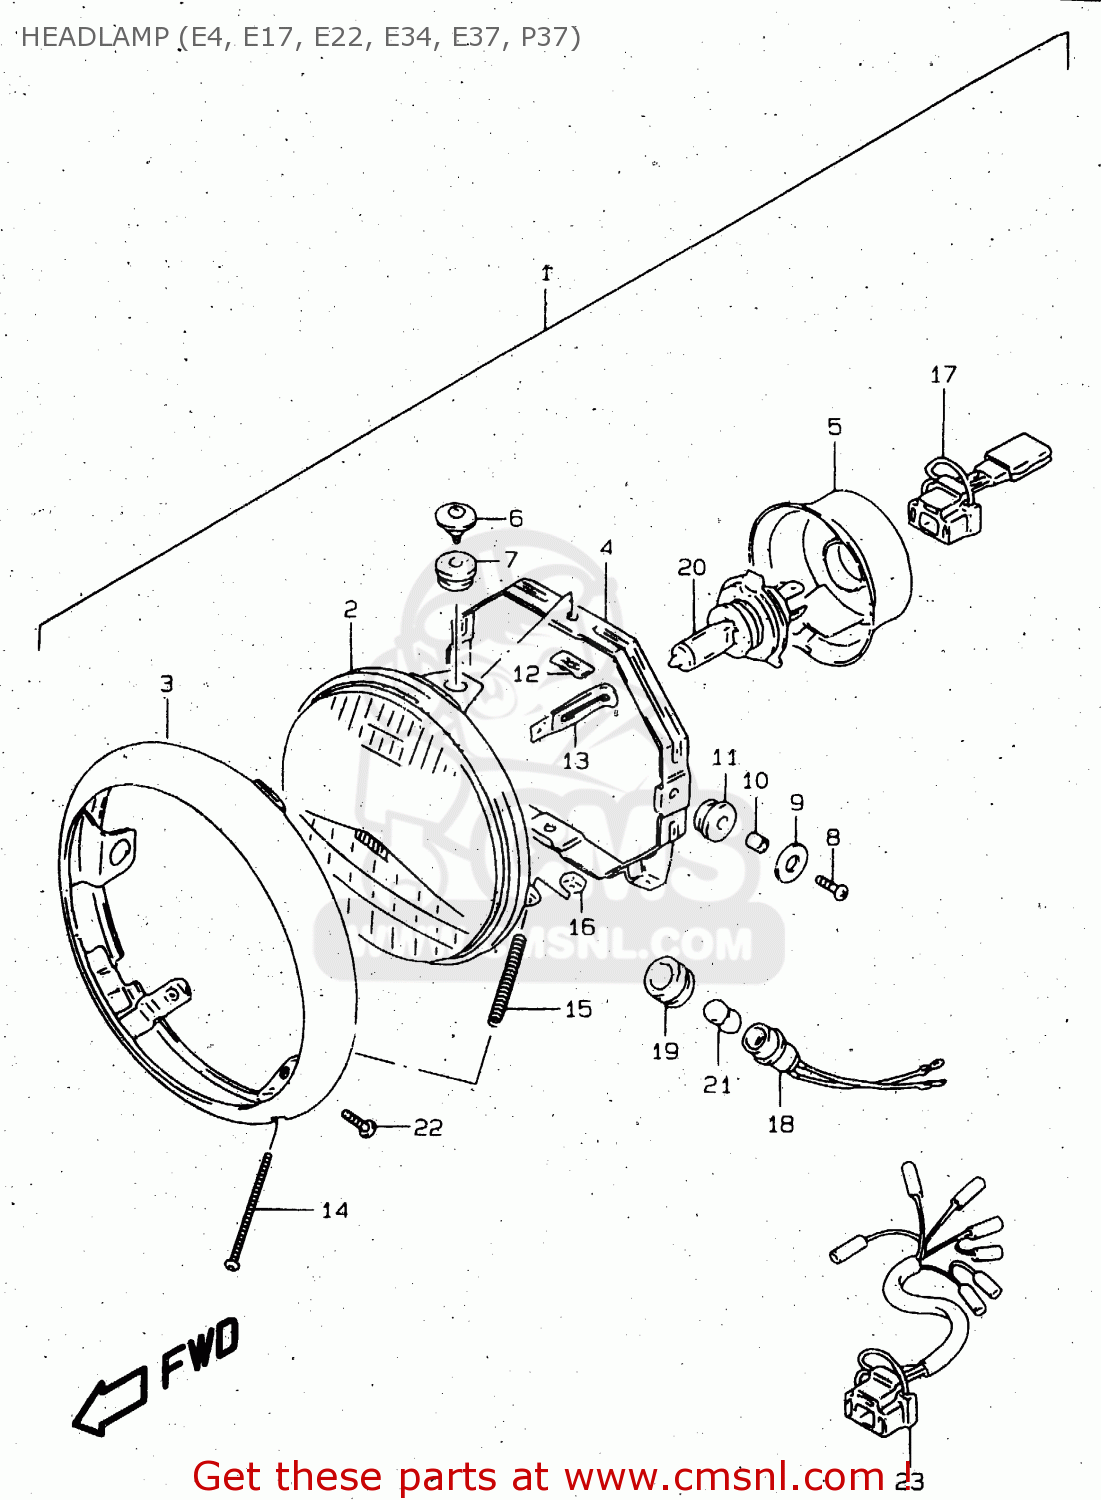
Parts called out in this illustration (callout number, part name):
1	HEADLAMP ASSY
2	UNIT
3	RIM
4	RING,MOUNTING
5	COVER,SOCKET
6	SCREW,MOUNTING
7	CUSHION
8	SCREW
9	WASHER(5.5X18X1)
10	SPACER
11	CUSHION
12	NUT
13	CLAMP(L:65)
14	SCREW,ADJUSTING(4X50)
15	SPRING
16	NUT
17	SOCKET
18	SOCKET
19	JOINT,RUBBER
20	BULB(12V60/55W,H4)
21	BULB(12V4W)
22	SCREW
23	WIRE,HEADLAMP LEAD
